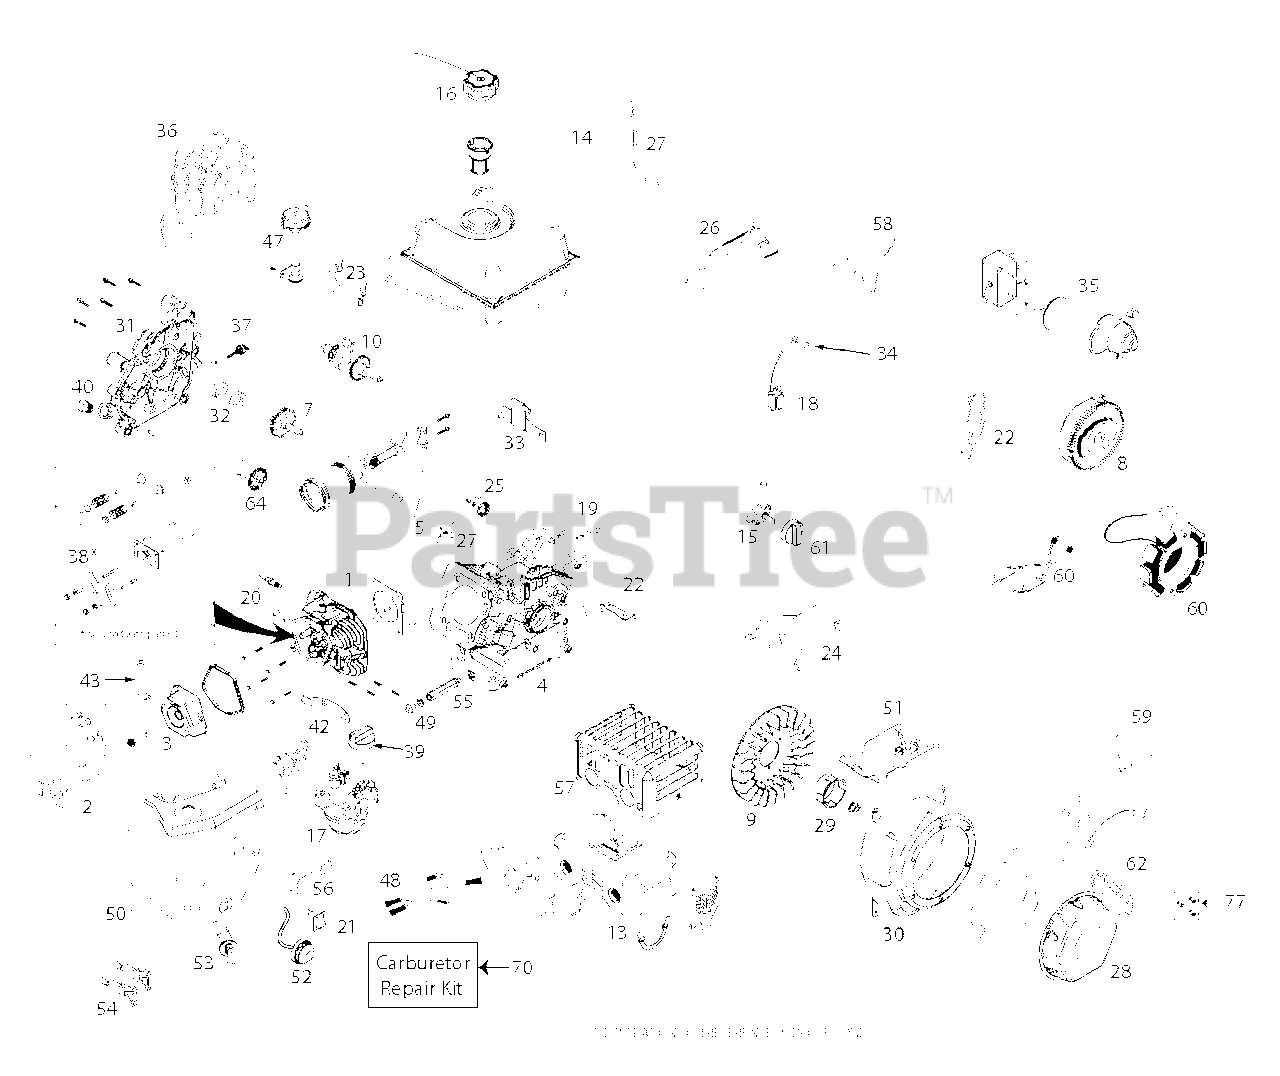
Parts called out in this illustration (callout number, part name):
1	CYLINDER.HEAD.ASSY(SK2911000)
2	PUSH ROD TAPPET KIT
3	VALVE.COVER(SK4144500)
4	CYLINDER ASSY SNOW
5	PISTON.AND.ROD.ASSY(SK2911400)
7	CAMSHAFT(SK2911600)
8	FLYWHEEL.EL.ST.SKSNO2401.1
9	FLYWHEEL.FAN
10	CRANKSHAFT.KEYED.SNOW.291CC.LC
13	MUFFLER.ASSY.SNOW(SKSN4200)
14	FUEL TANK ASSY - SNOW (291CC)
15	FUEL.PETCOCK.SNOW(SKSN4900)
16	FUEL.TANK.CAP.SNOW(SKSN4301)
17	CARBURETOR.ASSY.SNOW(SKSN2302)
18	IGNITION COIL ASSY
19	CDI.BOX.ASSY.SNOW(SKSN4404)
20	SPARK.PLUG(SK2911550)
21	ON/OFF.SWITCH.SNOW(SKSN4403)
22	SHIELD.U/FYWHL.CHARG(SKSN4604)
23	KIT.FUEL.HOSE.208CC.SING/STAGE
24	TOP.SHIELD.LCT.
25	GOVERNOR.GEAR.ASSY(SK2912900)
26	GOVERNOR.ARM.ASSY.(SKSN2502)
27	GOVERNOR.SHAFT.(SK2913100)
28	RECOIL.START.ASSY.(SKSN2600)
29	STARTER.CUP.SMALLSNOW(SKSN2601
30	HOUSING.BLOWER.ASM
31	CRANKCASE.COVER.ASY(SK2913600)
32	OIL.SEAL.KIT(SK2913900)
33	ELECTRIC.START.BRKT(SKSN4405)
34	SPARK.PLUG.BOOT.SNW,SKSN4691.1
35	ELECTRIC.START.ASSY(SKSN2400)
36	ENGINE.GASKET.KIT(SK2914300)
37	DIPSTK.OIL.BLK.LCTSK4143711.1
38	ROCKER ARM KIT
39	CHOKE.KNOW.SNOW(SKSN4500)
40	NONREMVABLE.OIL.PLUG(SK4143715
42	CDI.BOX.BRKT.SNOW(SKSN4402)
43	Breather Tube, LCT 291/369/414
47	HIGHOIL.FILL.ASSY.KIT(SKSN4911
48	WIRE.HARNESS(SKSN4406)
49	OIL.DRAIN.PLUG
50	HEATER.BOX.ASSY.SNOW(SKSN2100)
51	SHIELD.CYLINDER.SNOW(SK4141010
52	PRIMER.BULB.ASSY(SKSN4304)
53	KEY.SWITCH.ASSY.SNOW(SKSN4401)
54	KEY SET(2 KEYS) SKSN0407.1
55	EXTENDED OIL DRAIN TUBE
56	SHIELD.VAPOR(SKSN4606)
57	SHIELD.MUFFLER.
58	GOVERNOR.LINK.SHIELD(SKSN2501)
59	FUEL.TANK.SKIRT(SKSN2101)
60	ALTERN.60WATT.SKSN2402.1
61	FUEL KNOB-SNOW
62	STARTER.GRIP.SNOW(SKSN2603.1)
65	TAPPET KIT.LCT.SK2911005.1
70	Carburetor Repair Kit, 291CC/4
77	Recoil Bolt Kit, LCT
